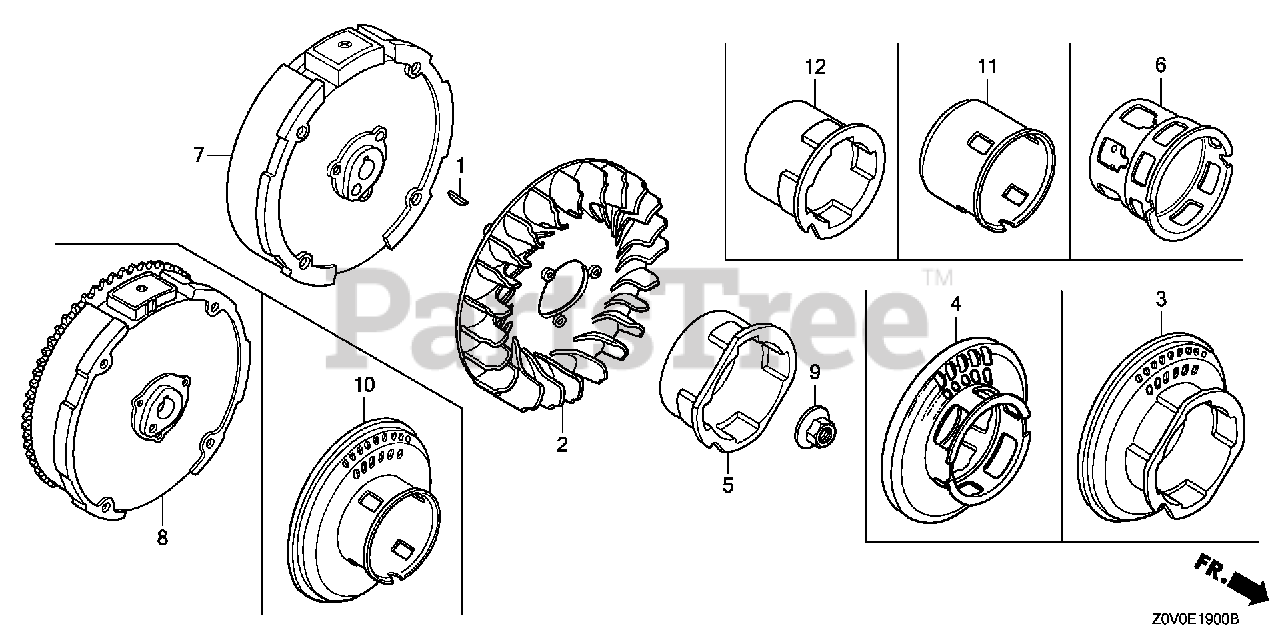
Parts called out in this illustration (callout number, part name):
1	KEY, SPECIAL WOODRUFF (25X18)
2	FAN, COOLING
5	PULLEY, STARTER
7	FLYWHEEL (STD)
9	NUT, SPECIAL (14MM)
11	PULLEY, STARTER
